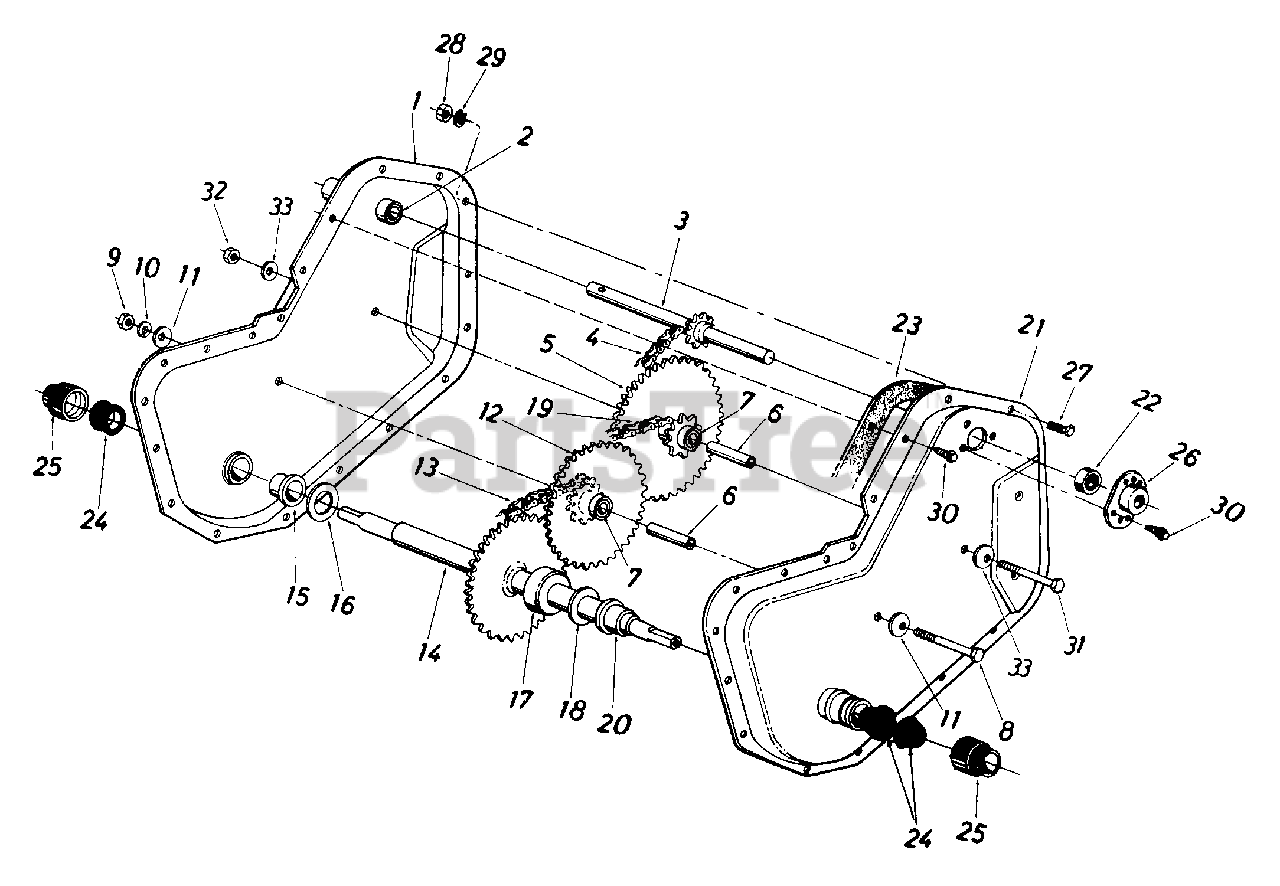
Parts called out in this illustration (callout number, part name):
1	Chain Case Half Ass'y.- R.H.
2	Bearing 5/8" I.D. x .813" O.D. x 1.31" Lg.
3	Input Shaft Ass'y.
4	Chain #35 - 3/8" Pitch x 44 Links
5	Sprocket and Hub Ass'y.
6	Bearing Inner Axle
7	Sleeve Brg. 5/8" I.D. x 3/4" O D. x 1.50
8	Hex Bolt 3/8-24 x 2.50" Lg.
9	Hex Ins. L-Nut 3/8-24 Thd.
10	L-Wash. 3/8" I.D.
11	Bell-Wash..41" I.D. x 1.13" O D. x .03
12	Sprocket & Hub Ass'y. 9T-22T
13	#420 Chain 1/2 Pitch x 28 Links Endless
14	Wheel Shaft Ass'y.
15	Flange Bearing
16	Fl-Wash..88" I.D. x 1.5" O D. x .03
17	Spacer 7/8" I.D. x 13/4" O.D. x .68" Lg.
18	Fl-Wash..88" I.D. x 1.50" O D. x.03
19	#420 Chain 1/2" Pitch x 30 Links Endless
20	Flange Bearing
23	Gasket
25	Dust Cup
26	Bearing Housing
27	Hex Bolt 1/4-28 x 5/8" Lg.
28	Hex Nut 1/4-28 Thd.
29	L-Wash. 1/4" I.D.
31	Hex Bolt 5/16-18 x 2.5" Lg.
32	Hex Cent. L-Nut 5/16-18 Thd.
33	Fl-Wash. 5/16" I.D.
